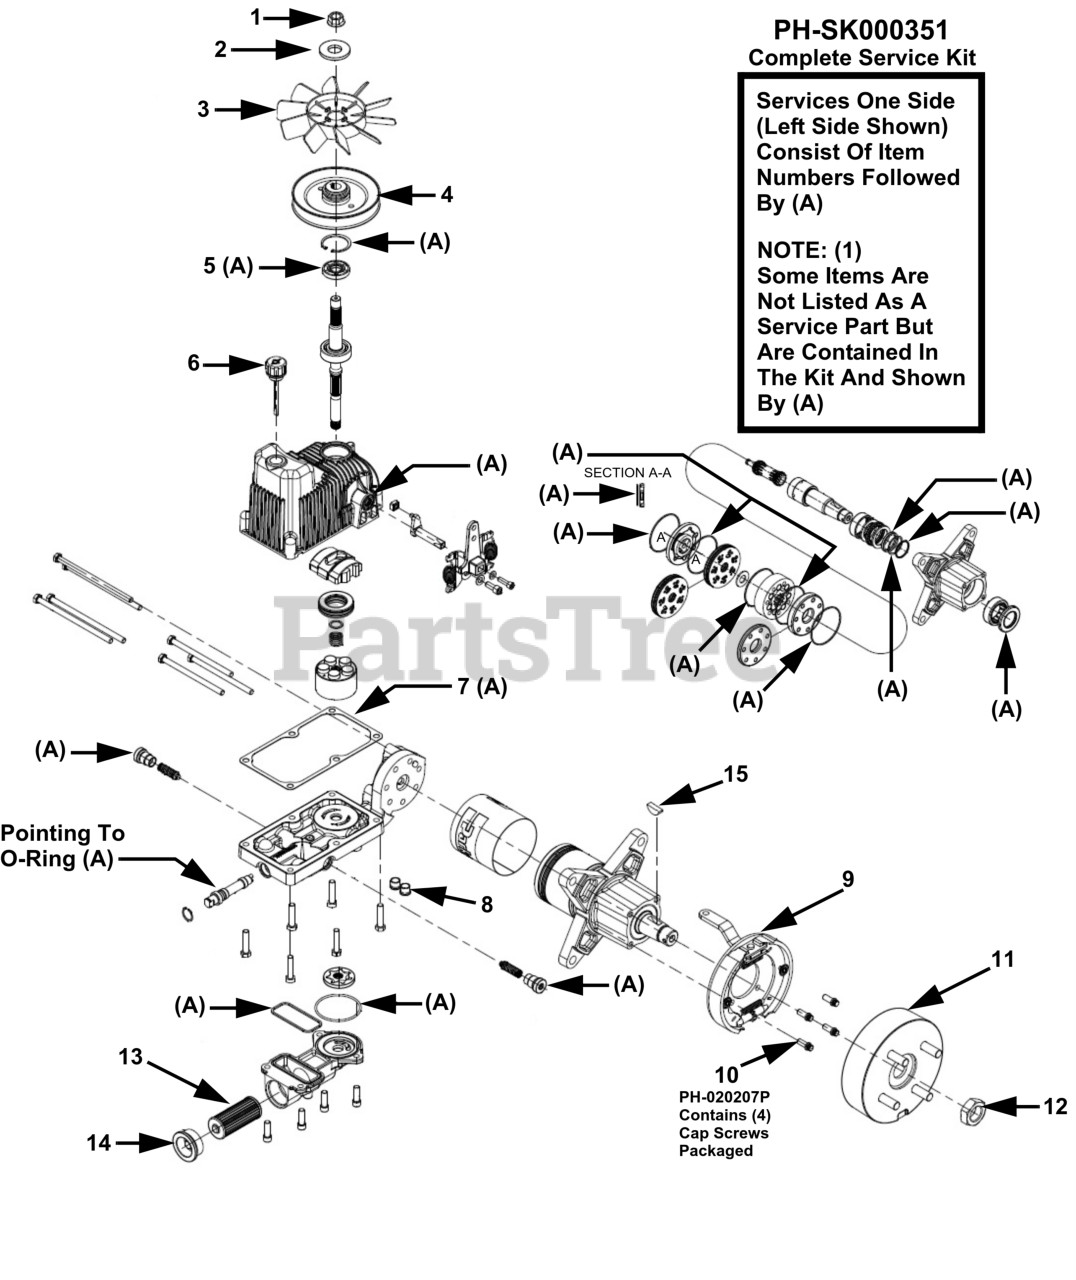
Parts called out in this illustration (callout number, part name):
1	NUT-FLANGE 1/2-20
2	SPACER-FAN
6	BREATHER
8	PLUG-MAGNETIC HEX
9	BRAKE ASSEMBLY-ON HOLE LEVER
10	SCREW-CAP (QTY 4)
11	DRUM-4 BOLT BRAKE
12	NUT-SLOTTED
14	PLUG & O-RING ASSE
15	WOODRUFF KEY
420112	RETURN SERVICE KIT
A	COMPLETE SEAL SERVICE KIT
